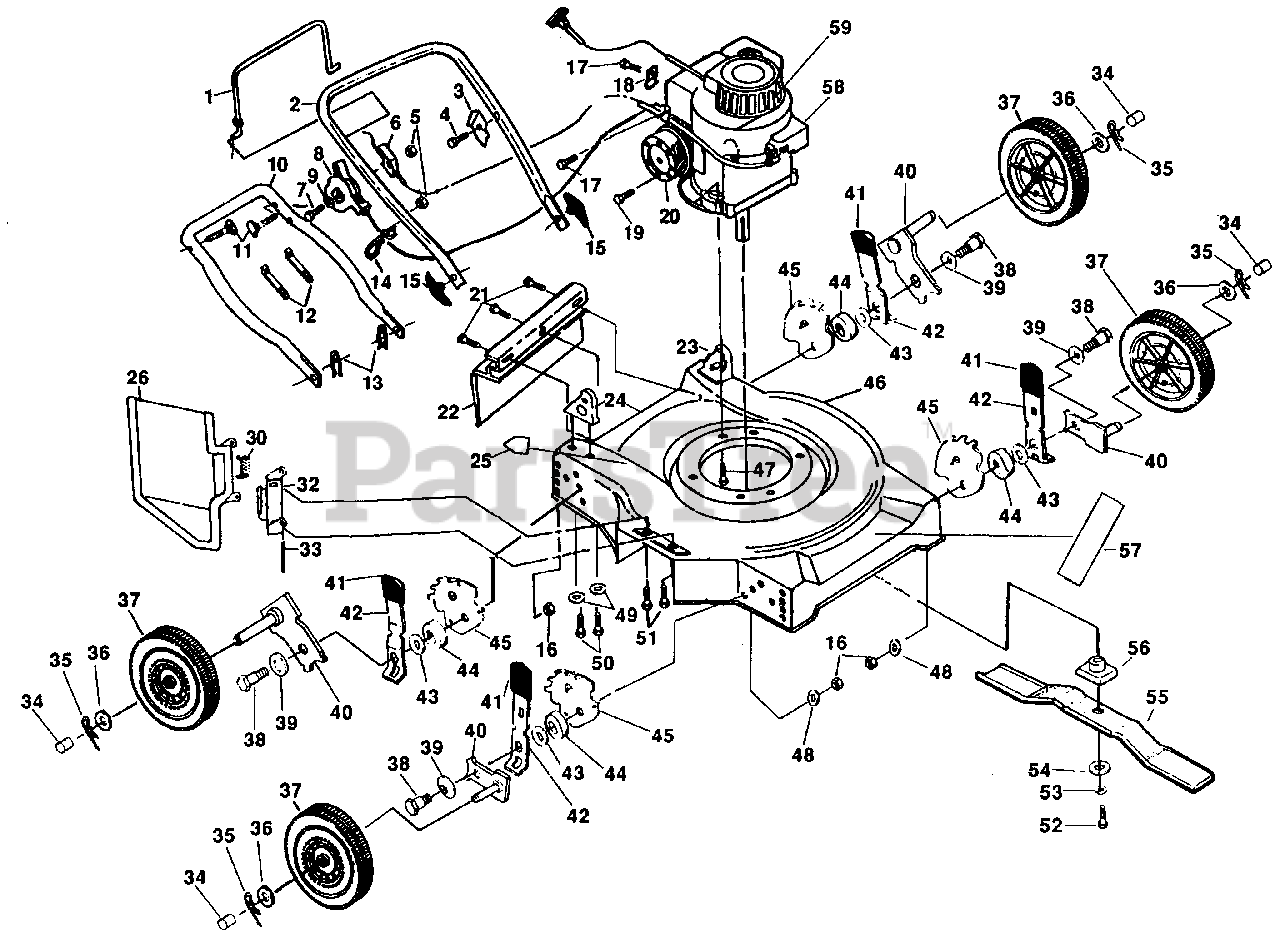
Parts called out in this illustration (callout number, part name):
1	Control Bar (AYP part number)
2	Upper Handle (AYP part number)
3	Up-Stop Bracket (AYP part number)
4	Hex Washer Head Screw #10-24 X 1/2 (AYP part number)
5	Locknut 1/4-20 (AYP part number)
6	Engine Zone Control Cable
7	Flat Washer 9/32 x 5/8 x 1/16 (AYP part number)
8	Throttle Control (AYP part number)
9	Machine Screw 1/4-20 x 2-1/8
10	Lower Handle (AYP part number)
11	Handle Bolt 5/16-18 x 1-3/4
12	Wire Tie (AYP part number)
13	Hairpin Cotter (AYP part number)
14	Rope Guide (AYP part number)
15	Handle Knob (AYP part number)
16	Locknut 3/8-16 (AYP part number)
17	Thread Rolling Screw #10-32 x 5/8 (AYP part number)
18	Cable Clamp (Engine) (AYP part number)
19	Screw #8-32 x 3/8 (AYP part number)
20	Muffler Deflector
22	Rear Skirt (AYP part number)
23	Handle Bracket Assembly (Left) (AYP part number)
24	Handle Bracket Assembly (Right) (AYP part number)
25	Danger Decal (AYP part number)
26	Discharge Guard (AYP part number)
27	Hex Head Thread Rolling w/Sems. 1/4-20 x 3/8 (AYP part number)
30	Torsi??on Spring (AYP part number)
32	Housing Bracket BEP (AYP part number)
33	Hinge Rod (AYP part number)
34	Hubcap (AYP part number)
35	Retainer Clip (AYP part number)
36	Flat Washer 1/2 (AYP part number)
37	Wheel Assembly 7.0 x 1-1/2
38	Shoulder Bolt 3/8-16 (AYP part number)
39	Belleville Washer 1/2 (AYP part number)
40	Axle Arm Assembly (AYP part number)
41	Selector Knob (AYP part number)
42	Selector Spring (AYP part number)
43	Flat Washer 3/8 (AYP part number)
44	Spacer (AYP part number)
45	Wheel Adjuster Bracket (AYP part number)
46	Lawn Mower Housing (Inc. Ref. #25)
47	Hex Head Thread Rolling Screw 3/8-16 x 1 (AYP part number)
48	Washer (AYP part number)
49	Flat Washer 5/16 (AYP part number)
50	Thread Cutting Screw 5/16-18 x 3/4 (AYP part number)
51	Hex Washer Head Tapping Screw #10-24 x 1/2 (AYP part number)
52	Hex Head Screw 3/8-24 x 1-3/8, Grade 8
53	Helicasl Spring Washer 3/8 (AYP part number)
54	Hardened Washer (AYP part number)
55	20" Blade
56	Blade Adapter (AYP part number)
57	Decal "Housing" (AYP part number)
59	Starter Guard
